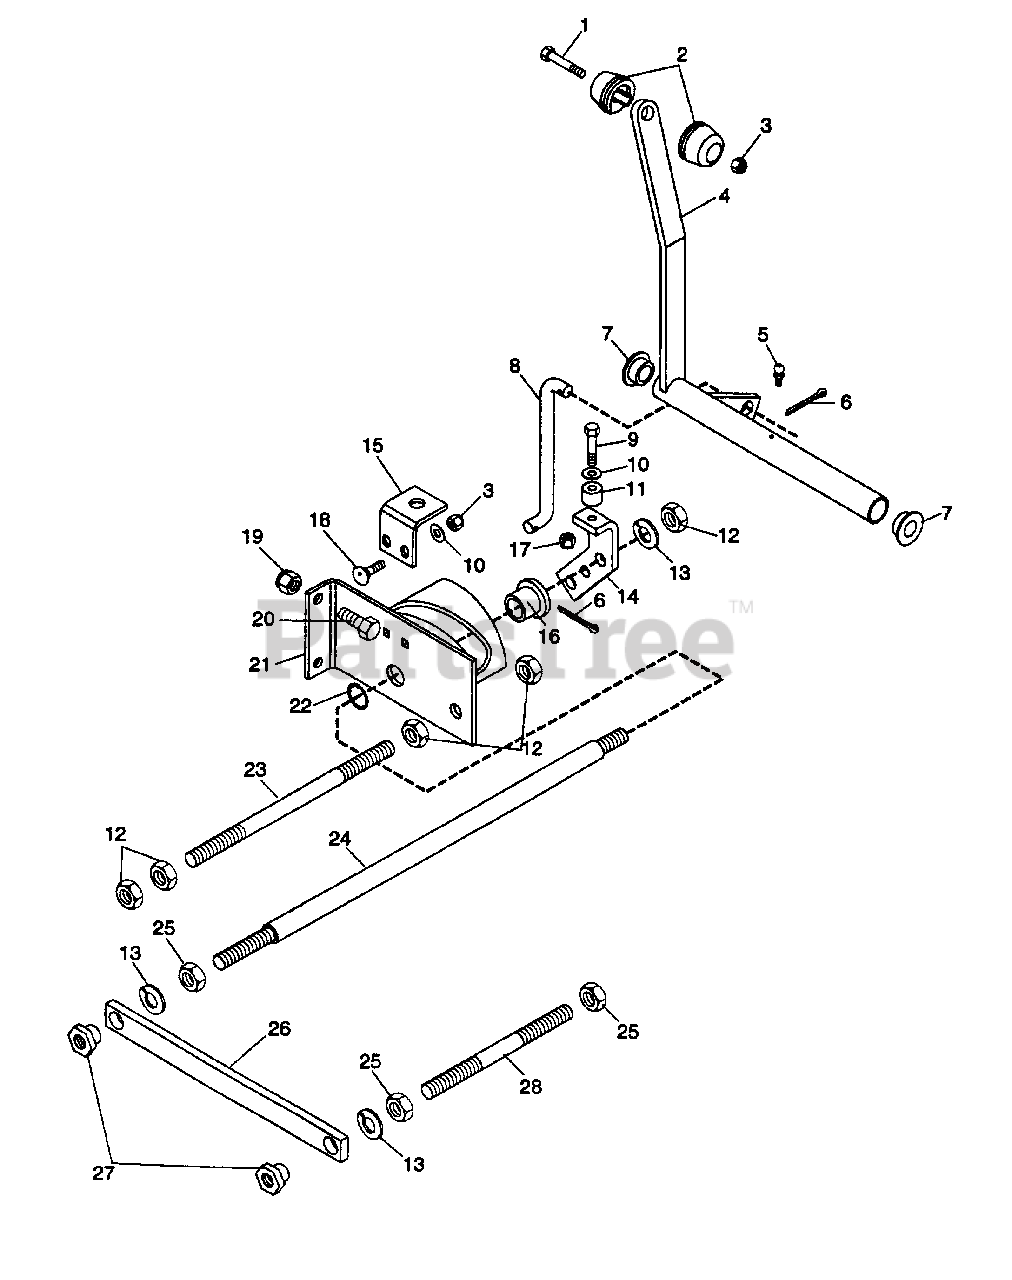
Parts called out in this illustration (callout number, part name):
1	BLT-HEX .25-20 X 1.50 PL GR 5
2	KNOB, CONTROL
3	NUT-LK-NYL .250-20 PL
4	CNTRL, PTO
5	FTG, LUBE; .25-28 SELF-THREAD
6	PIN-COTR .09 X 1.0 PL
7	BUSH., F .515 X 1.00 X .745 NY
8	ROD, PTO
9	BLT-HEX .25-28 X 1.38
10	WSHR-FL-STL .281 X .625 X .065
11	RLR, CLUTCH CAM; .250 X .750 X .5625
12	NUT .50-13 PL
13	WSHR-LOCK .500 X 1.51 HVY PL
14	ARM, PTO CLUTCH ROLLER
15	BRKT, INTERLOCK
16	BSHR-FLG .762 X 1.0 X .580 X 1.48 NY
17	NUT-LK-NYL .250-28 W/INSR
18	BLT-RDHDSQNK .25-20 X .75
19	NUT-LK-NYL .375-16 PL
20	BLT-HEX .38-16 X 1.00 PL GR 5
21	WLDMT, PTO BRKT
22	RG-RING-EXT 1.250 X .060
23	ROD, FRAME EXT BRACE
24	ROD, PTO
25	NUT-JAM .50-13 PL
26	SPRG, PTO
27	BUSH., F .500 X .875 X .700 ST
28	STUD, PTO
